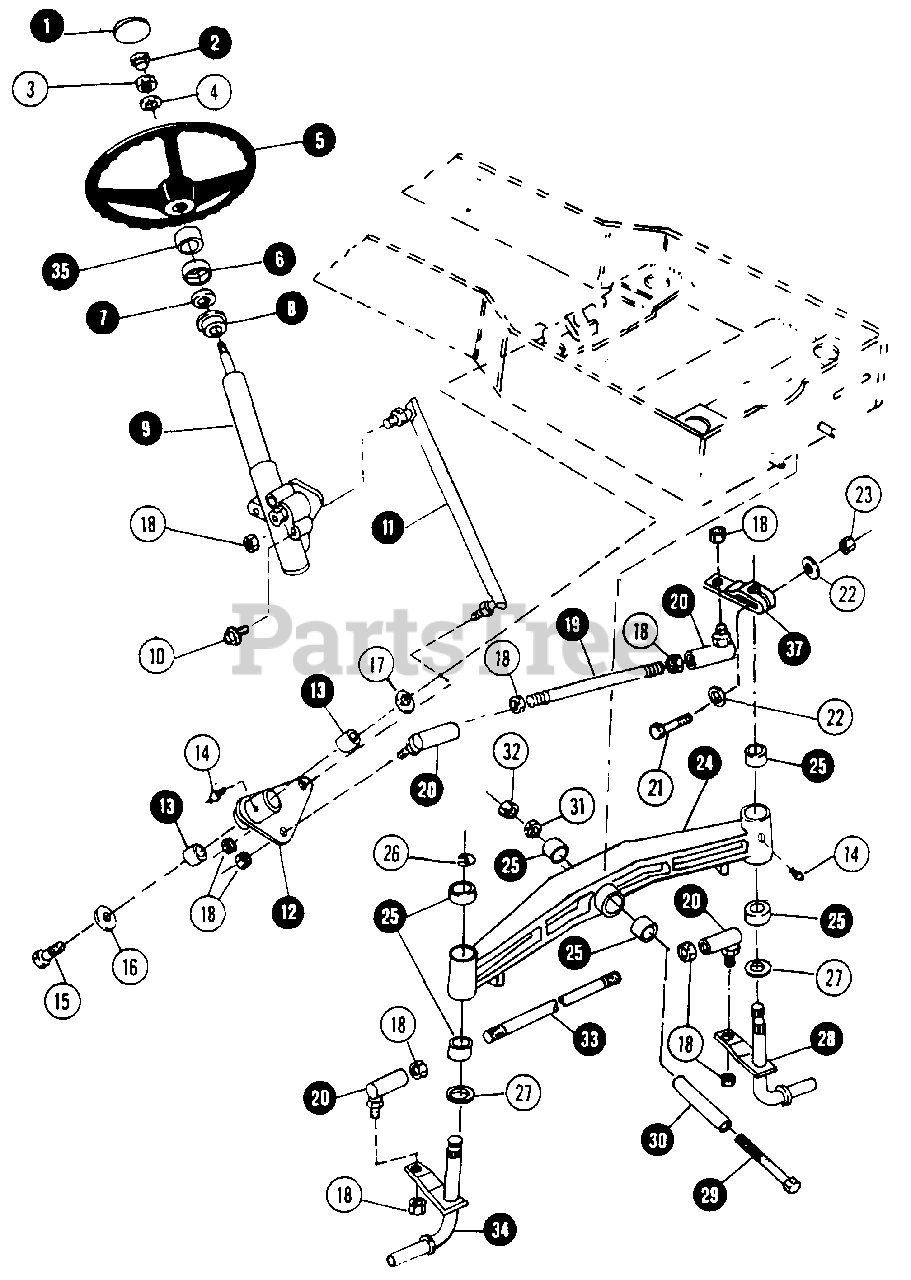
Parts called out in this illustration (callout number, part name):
1	PLATE, STEERING WHEEL COVER
2	TAPER-PLUG
3	NUT, 5/8
4	WASHER, 5/8 FLAT
5	WHEEL, STEERING
6	CAP, DUST (NLA)
7	COVER, DUST (NLA)
8	BEARING, STEERING COLUMN (NLA)
9	ASSEMBLY, STEERING GEAR (NLA)
10	CAPSCREW, 3/8-16 x 1
11	TIE-ROD, GEAR TO BELLCRANK (NLA)
12	ASSEMBLY, BELLCRANK
13	BEARING, SLEEVE
14	FITTING, Lube (Press fit for .187 hole-no ball)
15	CAPSCREW, 3/8C x 3/4 HEX LOCK
16	WASHER, THRUST
17	WASHER, THRUST (NLA)
18	NUT, 1/2-20
19	TIE-ROD, UPPER (NLA)
20	BALL JOINT
21	CAPSCREW, 3/8C x 2
22	WASHER, 13/32 x 1 x 1/8
23	NUT, 3/8C HEX
24	ASSEMBLY, FRONT AXLE (NLA)
25	BUSHING, AXLE
26	RING, SNAP
27	WASHER, THRUST
28	SPINDLE, LEFT (KING PIN)
29	CAPSCREW, 1/2C x 5 - 1/4 HEX HEAD
30	JOURNAL, PIVOT
31	NUT, 1/2C HEX
32	NUT, 1/2C HALF-HEX
33	TIE-ROD, LOWER (NLA)
34	SPINDLE, RIGHT (KING PIN)
35	SLEEVE, STEERING
37	ARM, Steering (NLA)
